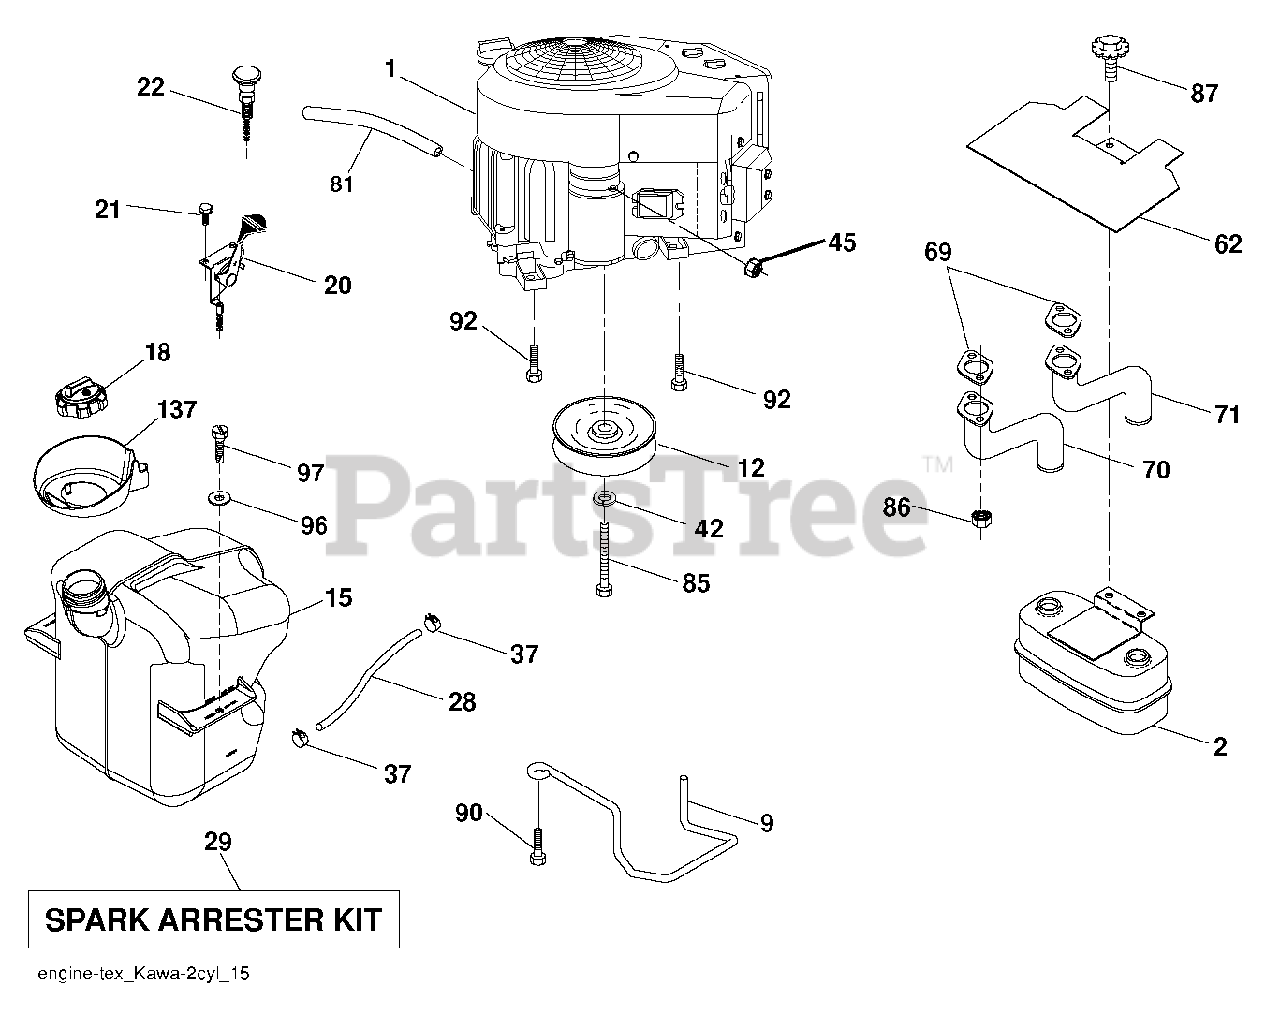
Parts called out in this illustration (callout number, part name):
2	MUFFLER.TWIN.CYL.LOW.TONE
9	KEEPER.BELT.ENGINE.4.2
12	PULLY ENGINE
15	FUEL TANK TANK. ASSEMBLY. EXTE
18	CAP.ASM.FUEL.2.25"TOP.TURN
20	THROTTLE CABLE
21	SCREW.#10 X 0.750.BOS
22	CONTROL.CHOKE.ERGO.PUSH-IN.BLA
28	LINE.FUEL.20
29	KIT.SPARK ARRESTOR 794945 B&S
37	HOSE CLAMP
42	LOCKWASHER
45	NUT
62	SHIELD.HEAT.MUFFLER
70	TUBE.EXHAUST.LH.FR961/FR730
71	TUBE.EXHAUST.RH.FR961/FR730
81	TUBE, DRAIN OIL ASM.
85	BOLT HEX 7/16-20X4-1/4"
86	NUT.HEX.FLANGE.TOPLOCK
87	Bolt, 5/16-18 X 1-3/4
90	SCREW 3/8-16X1
92	SCREW 3/8-16X1
96	WASHER
97	SCREW HEXWSHR 1/4-20X3/4
